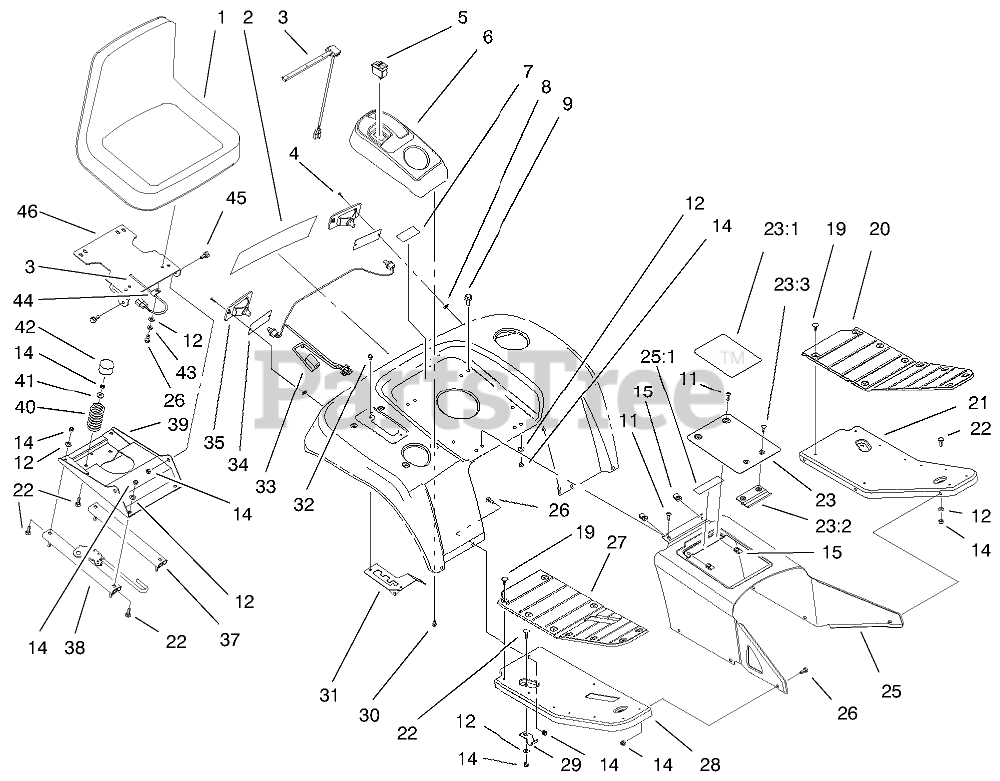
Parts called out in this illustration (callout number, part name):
1	Seat (Only On: 73470)
1	Seat V-811 (Only On: 73540, 73541)
2	DECAL - FENDER
3	SWITCH-SEAT
4	SCREW-PPH
5	Switch Cruise (Only On: 73540, 73541)
6	Pod-Control (Only On: 73540)
6	Pod-Control (Only On: 73541)
6	Pod-Control (Only On: 73470)
7	Decal-USA (Only On: 73470, 73540)
8	NUT-SPEED
9	SCREW-HHF
11	SCREW-HH
12	WASHER-PLAIN
14	NUT-LOCK, NI
16	Decal-Danger (Only On: 73470, 73540)
19	FASTENER-PANEL
20	PAD-FOOTREST, LH
21	FOOTREST-LH
22	SCREW-CARR
23	Tunnel Cover ASM (Only On: 73470, 73540)
23	Tunnel Cover ASM (Only On: 73541)
23:1	Decal-Danger (Only On: 73470, 73540)
23:1	Decal-Danger (Only On: 73541)
23:2	RETAINER-COVER
23:4	SCREW-PPH
25	Tunnel ASM (Only On: 73470, 73540)
25	Tunnel ASM (Only On: 73541)
25:1	Decal-Danger (Only On: 73470, 73540)
25:1	Decal-Warning (Only On: 73541)
26	SCREW-HH
27	PAD-FOOTREST, RH
28	FOOTREST-RH
29	BRACKET-FOOTREST
30	SCREW-HHFTF
31	GATE-HI / LO SHIFT
32	SCREW-HWH
33	Harness-Rear (Only On: 73540, 73541)
34	Gasket-Tail Light (Only On: 73470)
35	Lamp-Taillight (Only On: 73540, 73541)
35	Reflector (Only On: 73470)
37	SLIDE-SLAVE, SEAT
38	SLIDE-LATCH, SEAT
39	Base-Seat
40	SPRING-COMPRESSION
41	BUSHING
42	CAP-SPRING, SEAT
43	WASHER-LOCK
44	CLAMP-R
45	BOLT-SHOULDER
46	Mount-Seat
